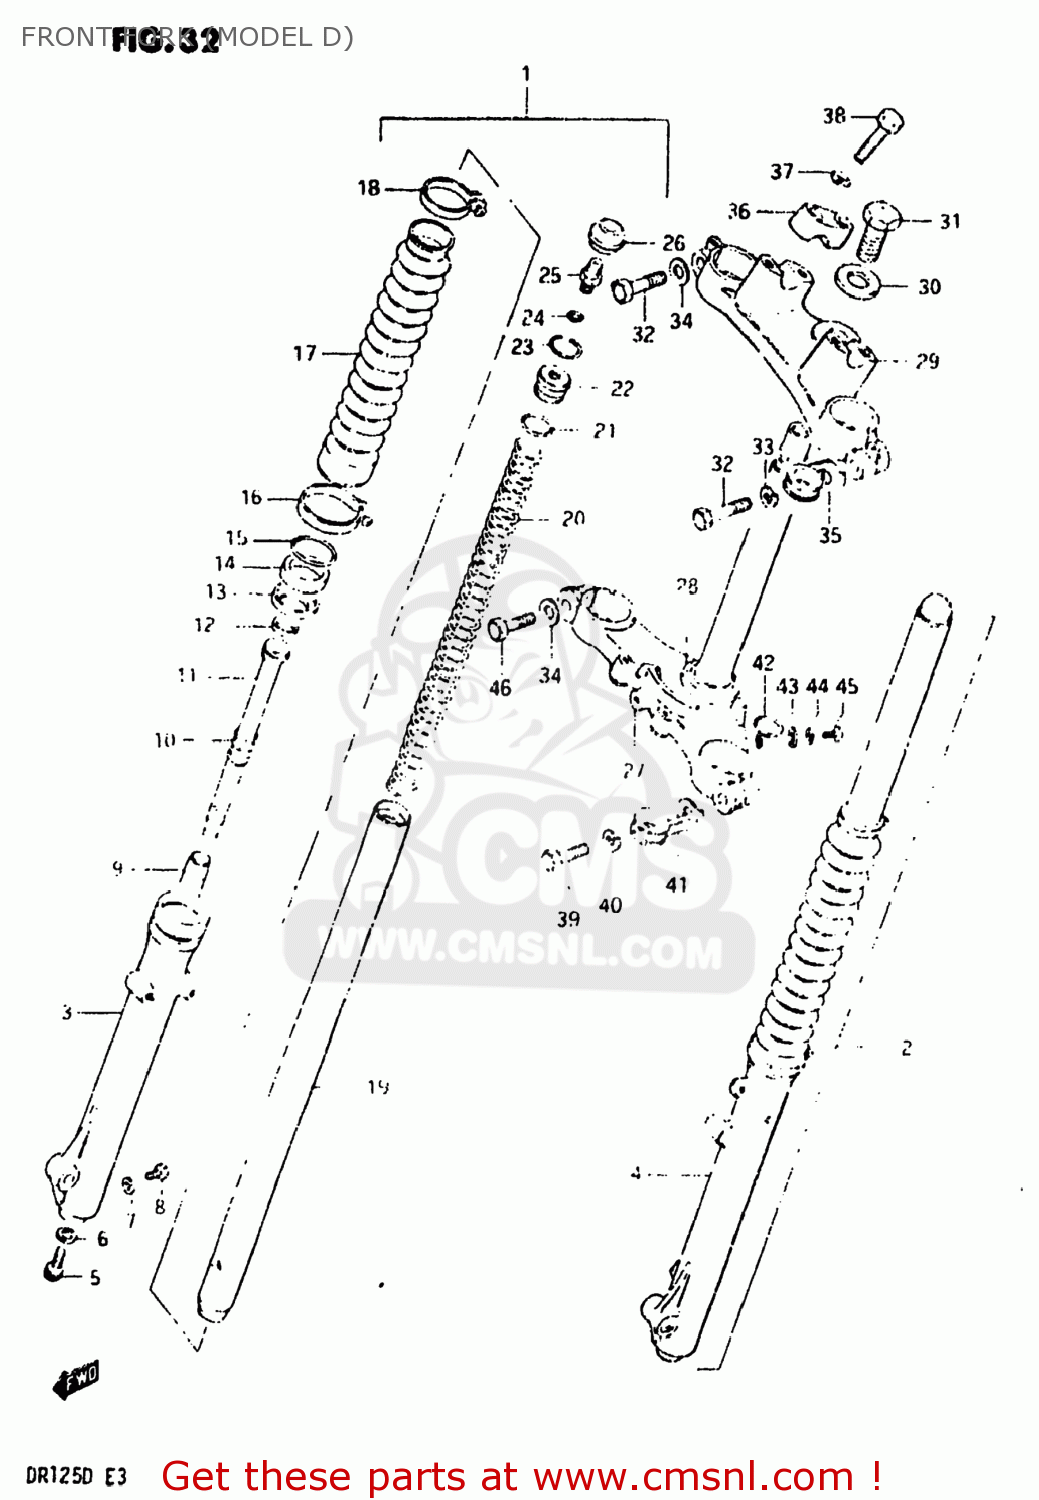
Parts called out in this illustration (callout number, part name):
1	DAMPER ASSEMBLY,RIGHT
2	DAMPER ASSEMBLY,LEFT
3	TUBE,FORK,OUTER,RIGHT
4	TUBE,OUTER,LEFT
5	BOLT(8X27)
6	GASKET (NAS)
7	GASKET,DRAIN,PLUG (NAS)
8	BOLT
9	PIECE,OIL LOCK
10	SPRING,REBOUND
11	CYLINDER,FR FORK
12	RING,PISTON
13	SPACER
14	OIL SEAL,FRONT FORK
15	RING,OIL SEAL STOPPER
16	CLAMP
17	BOOT
18	BAND
19	TUBE,FORK INNER
20	SPRING,FRONT FORK
21	O RING
22	SEAT,SPRING
23	RING,STOPPER
24	O-RING
25	VALVE,AIR
26	CAP,FRONT FORK
27	STEM,STEERING
28	RACE,STEERING OUTER LWR
29	HEAD,STEERING STEM
30	WASHER
31	BOLT,STEERING STEM HEAD
32	BOLT 10X40
33	LOCK WASHER
34	WASHER
35	GUIDE,CABLE
36	HOLDER,HANDLEBAR
37	LOCK WASHER
38	BOLT,HANDLE HOLDER
39	BOLT 12X45
40	WASHER,LOCK 12
41	GUIDE,CABLE
42	CLIP
43	WASHER
44	LOCK WASHER
45	SCREW 6X12
46	BOLT
